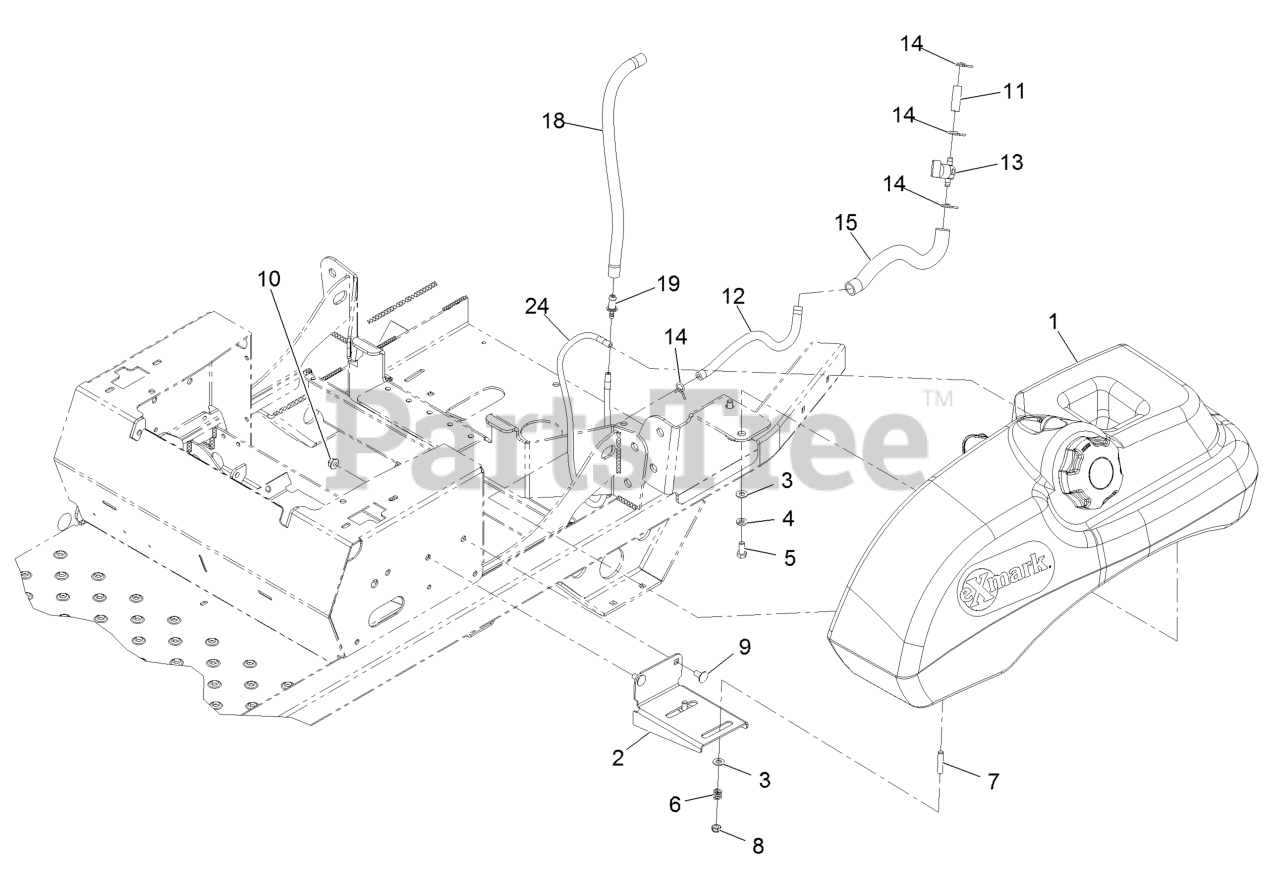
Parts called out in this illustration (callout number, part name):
1	ASM-FUEL TANK
2	BRACKET-TANK AND FENDER
3	WASHER-PLAIN
4	WASHER-LOCK
5	SCREW-HH
6	SPRING-TANK, FUEL
7	STUD
8	NUT-LOCK, NI
9	SCREW-CARR
10	NUT-HF, NI
11	HOSE-FUEL
12	HOSE-FUEL
13	VALVE-FUEL
15	CONDUIT-FUEL LINE
18	HOSE-FUEL
19	FITTING-ORIFICE, STRAIGHT
24	HOSE,EMISSIONS
